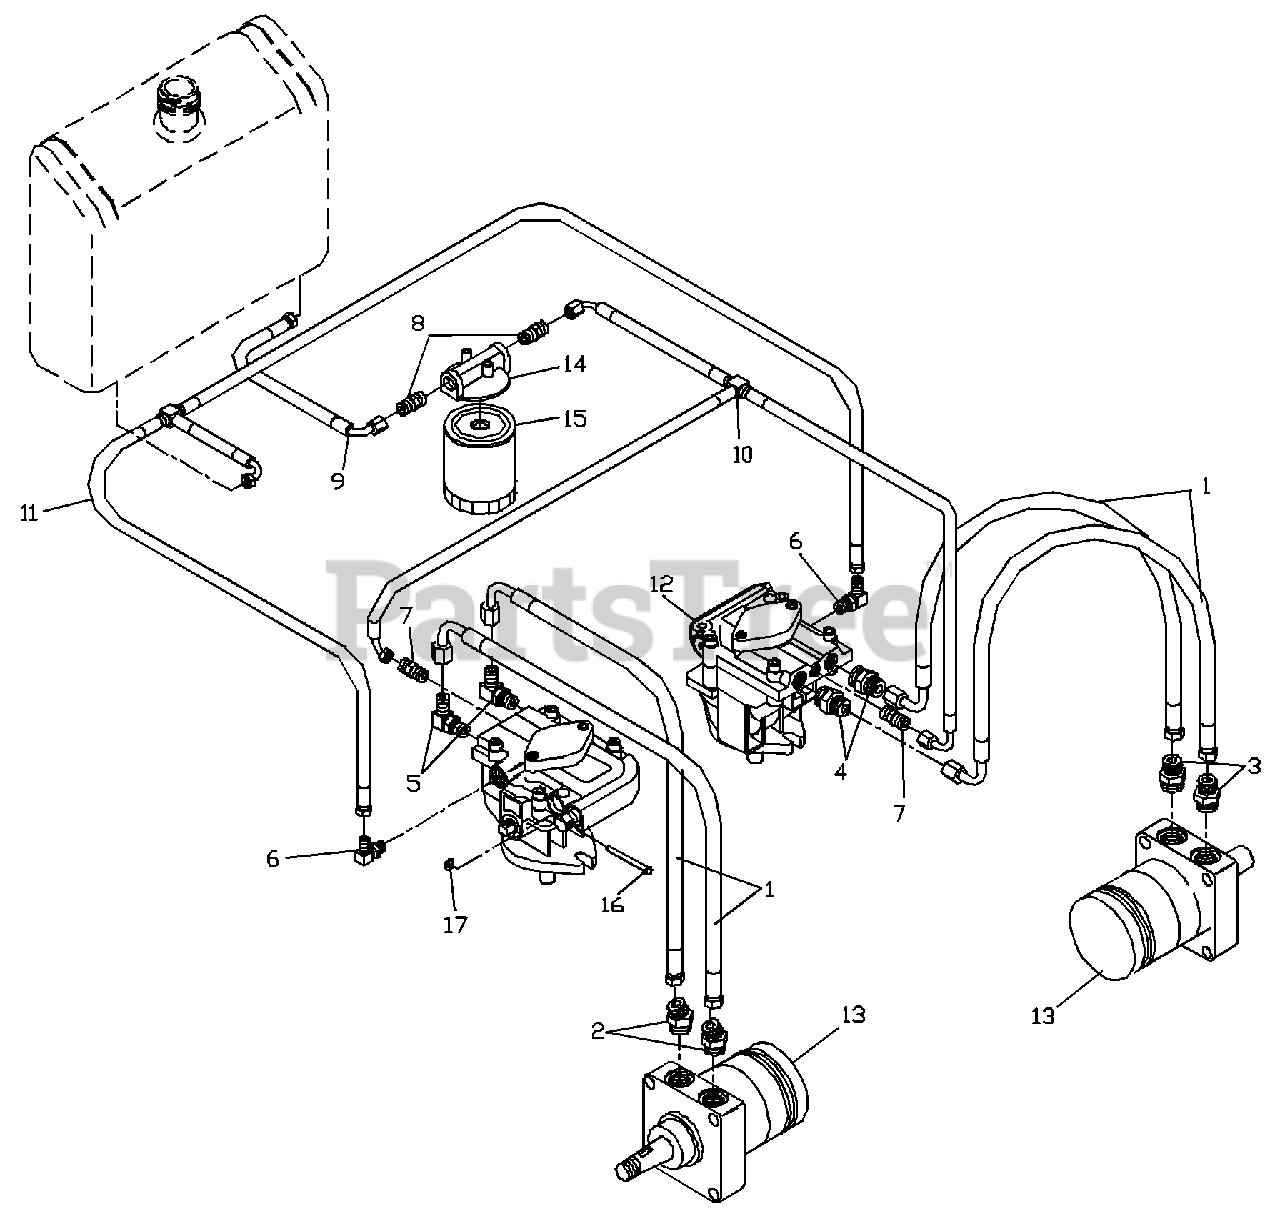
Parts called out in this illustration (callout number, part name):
1	1/2" HYDRAULIC HOSE
2	45 DEG. ELBOW
3	STRAIGHT CONNECTOR
4	STRAIGHT CONNECTOR
5	90 DEG. ELBOW
6	90 DEG. ELBOW
7	STRAIGHT CONNECTOR
8	STRAIGHT CONNECTOR
9	HOSE
10	INLET TEE HOSE
11	RETURN TEE HOSE
13	WHEEL MOTOR
14	FILTER HEAD
16	CLEVIS PIN
